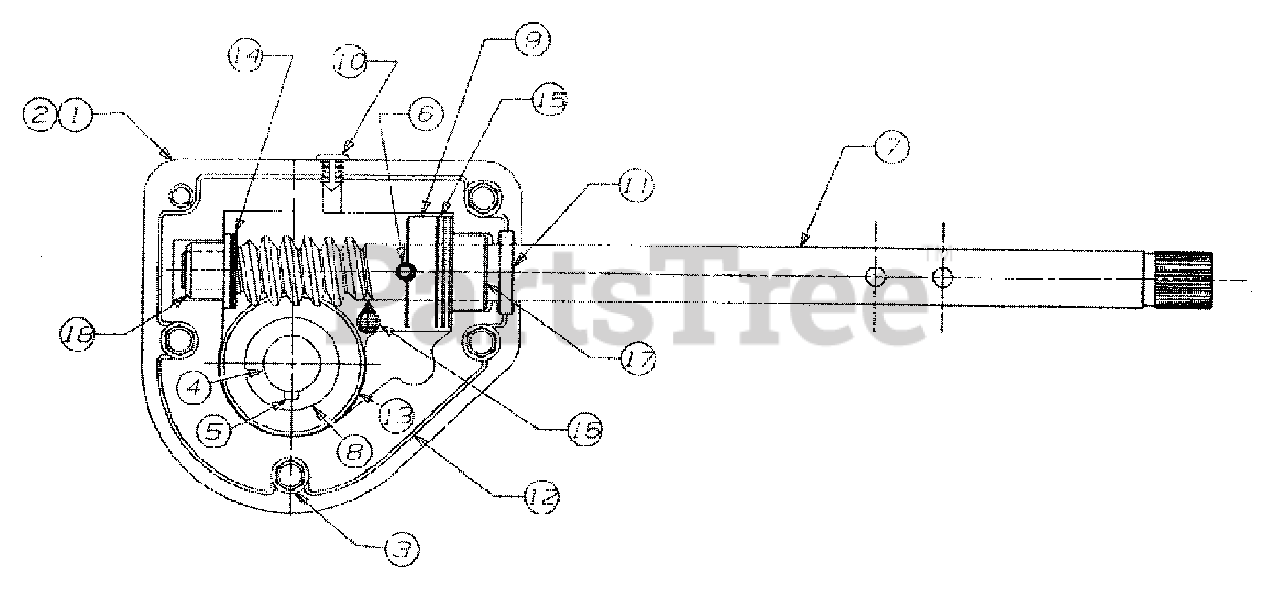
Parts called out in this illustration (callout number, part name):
1	Housing - R.H.
2	Housing - L.H.
3	Screw
4	Axle, Spiral 30"
4	Axle, Spiral 26"
4	Axle, Spiral 24"
4	Axle, Spiral 22"
5	Key, Hi-Pro
6	Pin, Spiral
7	Worm, Shaft
8	Gear, Worm
9	Collar, Thrust
11	Seal, Oil
12	Loctite 5699
13	Washer-Flat
14	Washer-Flat
15	Washer-Flat
16	Grease
17	Bearing Flange
18	Bearing Flange
